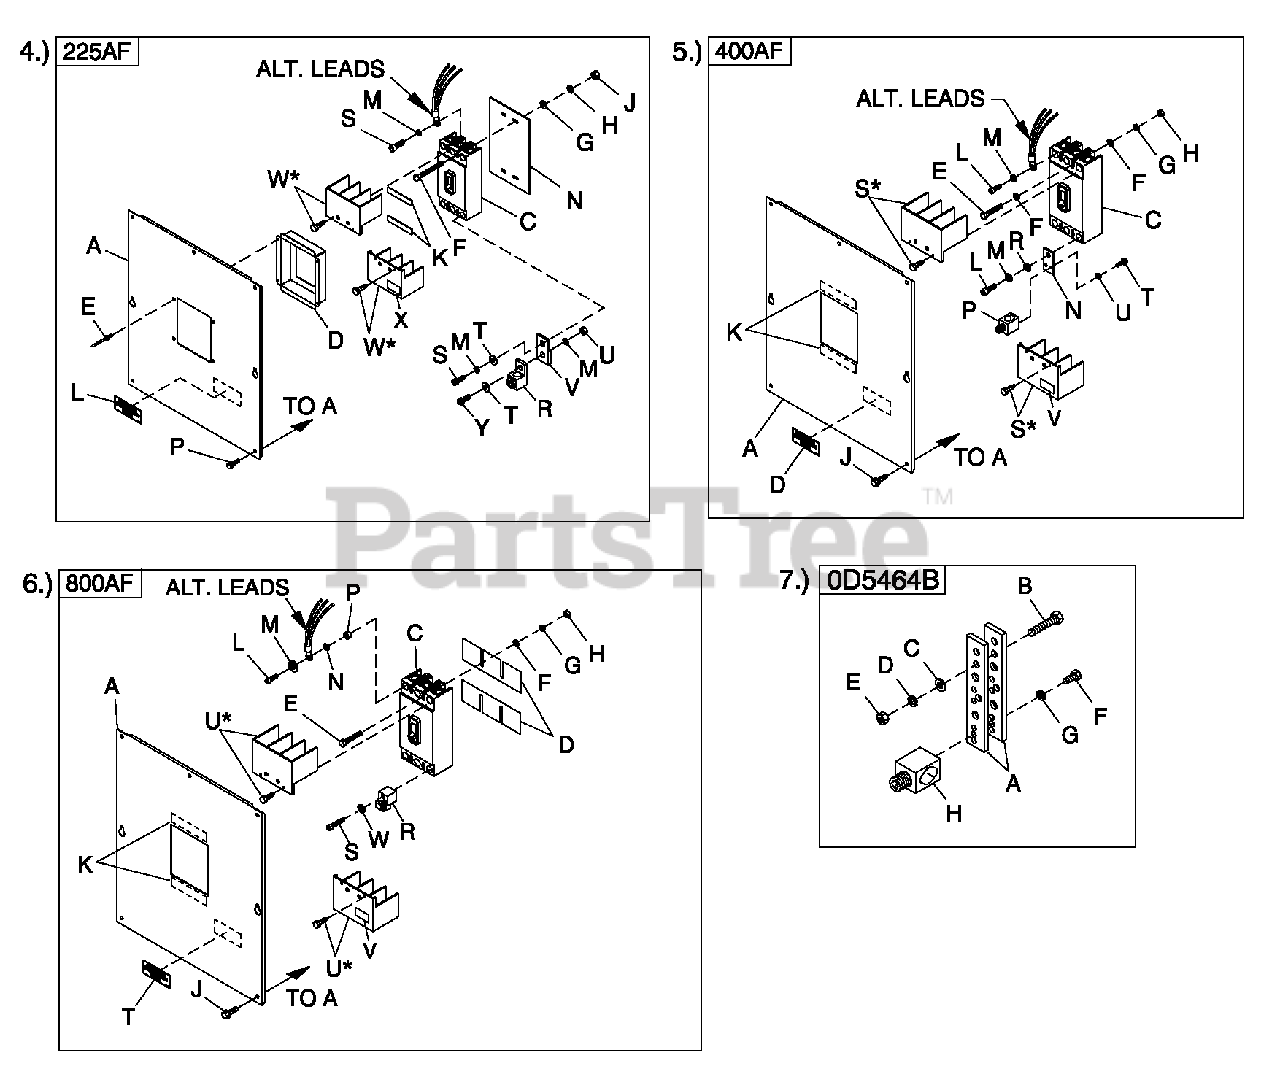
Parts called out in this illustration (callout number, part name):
A	COVER C BC5 225AF
C	CIRCUIT BREAKERS 200A FRAME
D	COVER CB DISH 225AF
E	RIVET PO P .125 X .275 SS
F	SCREW RHM #8-32X3-1/4
G	WASHER FLAT #8 ZINC
H	WASHER LOCK #8-M4
J	NUT HEX #8-32 STEEL
K	TAPE ELEC 1/2 FOAM
L	DECAL CUSTOMER CONNECT INSIDE
M	WASHER LOCK M8-5/16
N	INSULATOR CB225AF
P	SCREW THF M6-1 X 16 N WA Z/JS
R	LUG SLDLSS 300 MCM-6 AL/CU
S	SCREW SHC M8-1.25X20G8
T	WASHER FLAT 5/16-M8 ZINC
U	NUT HEX M8-1.25 G8 CLEAR ZINC
V	BUS BAR 200A LUG ADAP TOR
W	TERMINAL COVER CB
X	DECAL TERMINAL SHOCK HZD BI
Y	SCREW SHC M8-1.25X25G12.9
A	COVER C BC5 400AF
C	CIRCUIT BREAKERS 400A FRAME
D	DECAL CUSTOMER CONNECT INSIDE
E	SCREW RHM 1 0-32X4
F	WASHER FLAT #10 ZINC
G	WASHER LOCK #10
H	NUT HEX #10-32 STEEL
J	SCREW THF M6-1 X 16 N WA Z/JS
L	SCREW SHC M10-1.5X25G12.9
M	WASHER LOCK M10
N	BUS BAR CB ADAP TER 225-400 A
P	LUG SLDLSS 600/250-1/0 X 1/4-28
R	WASHER FLAT 3/8-M10 ZINC
S	TERM COVER CB
T	SCREW HHC 1/4-28 X 1/2 G5
U	WASHER LOCK M6-1/4
V	DECAL TERMINAL SHOCK HZD BI
A	COVER C BC5 800AF
C	CIRCUIT BREAKERS 800A FRAME
D	INSULATOR CB800AF
E	SCREW RHM 1/4-20X3-1/2
F	WASHER FLAT 1/4-M6 ZINC
G	WASHER LOCK M6-1/4
H	NUT HEX 1/4-20 STEEL
J	SCREW THF M6-1X16 N WA Z/JS
L	SCREW SHC M10-1.50X 40 G12.9
M	WASHER FLAT 3/8-M10ZINC
N	WASHER LOCK 3/8
P	NUT HEX M10-1.5 G8YEL CHR
R	LUG SLDLSS 3/0-400X3 MCM AL/CU
S	SCREW SHC M6-1.0X50G8.8
T	DECAL CUSTOMER CONNECT INSIDE
U	TERM COVERVITZROTECH 400AF CB
W	WASHER LOCK M6-1/4
A	BUS BAR NEUTRAL BLOCK 390
B	SCREW HHC M8-1.25 X 45 G8.8 FT
C	WASHER FLAT 5/16-M8ZINC
D	WASHER LOCK M8-5/16
E	NUT HEX M8-1.25 G8YEL CHR
F	SCREW HHC 1/4-28 X 3/4 G5
H	LUG SLDLSS 600/250-1/0X1/4-28
